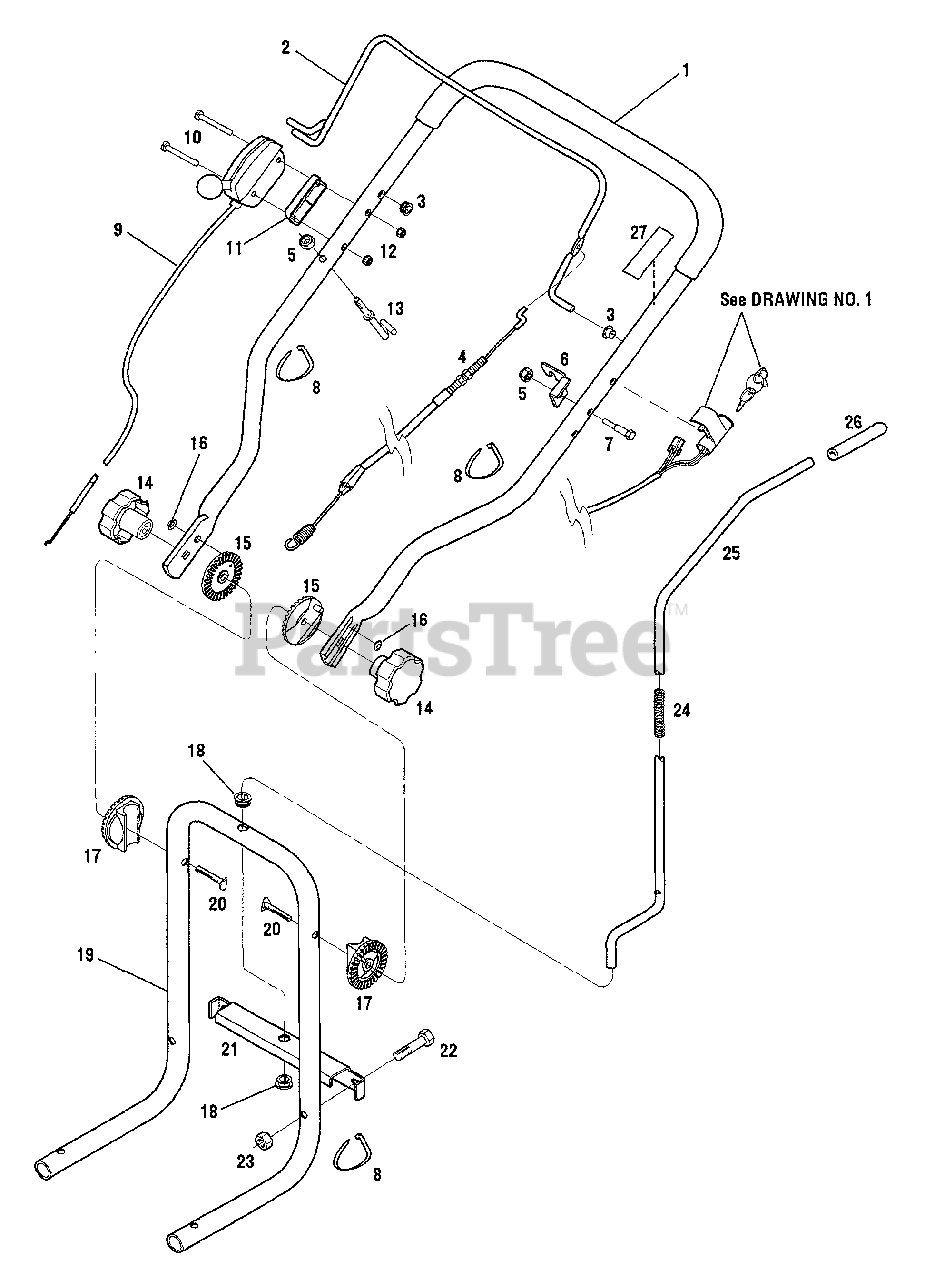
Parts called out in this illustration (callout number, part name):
1	Handlebar
2	Control Bail - Trimmer Head
3	Nyliner Bushing
4	Cable Assembly - Trimmer Head
5	Top Locknut, 1/4-20
6	Cable Bracket
7	Hex Hd. Screw, 1/4-20 x 1-1/8
8	Cable Tie
9	Throttle Control & Cable
10	Pan Hd. Screw, #10-24 x 2
11	Spacer
12	Hex Locknut, #10-24
13	Starter Rope Guide
14	Height Adjust Knob
15	Height Adjust Quadrant-Outside
16	Push-on Retainer
17	Height Adjust Quadrant-Inside
18	Nyliner Bushing
19	Handlebar Support
20	Curved Hd. Screw, 5/16-18 x 2
21	Bracket - Handlebar Support
22	Hex Hd. Screw, 5/16-18 x 1-3/4
23	Hex Locknut, 5/16-18
25	Parallel Trim Lever
27	Decal-Bail Control
